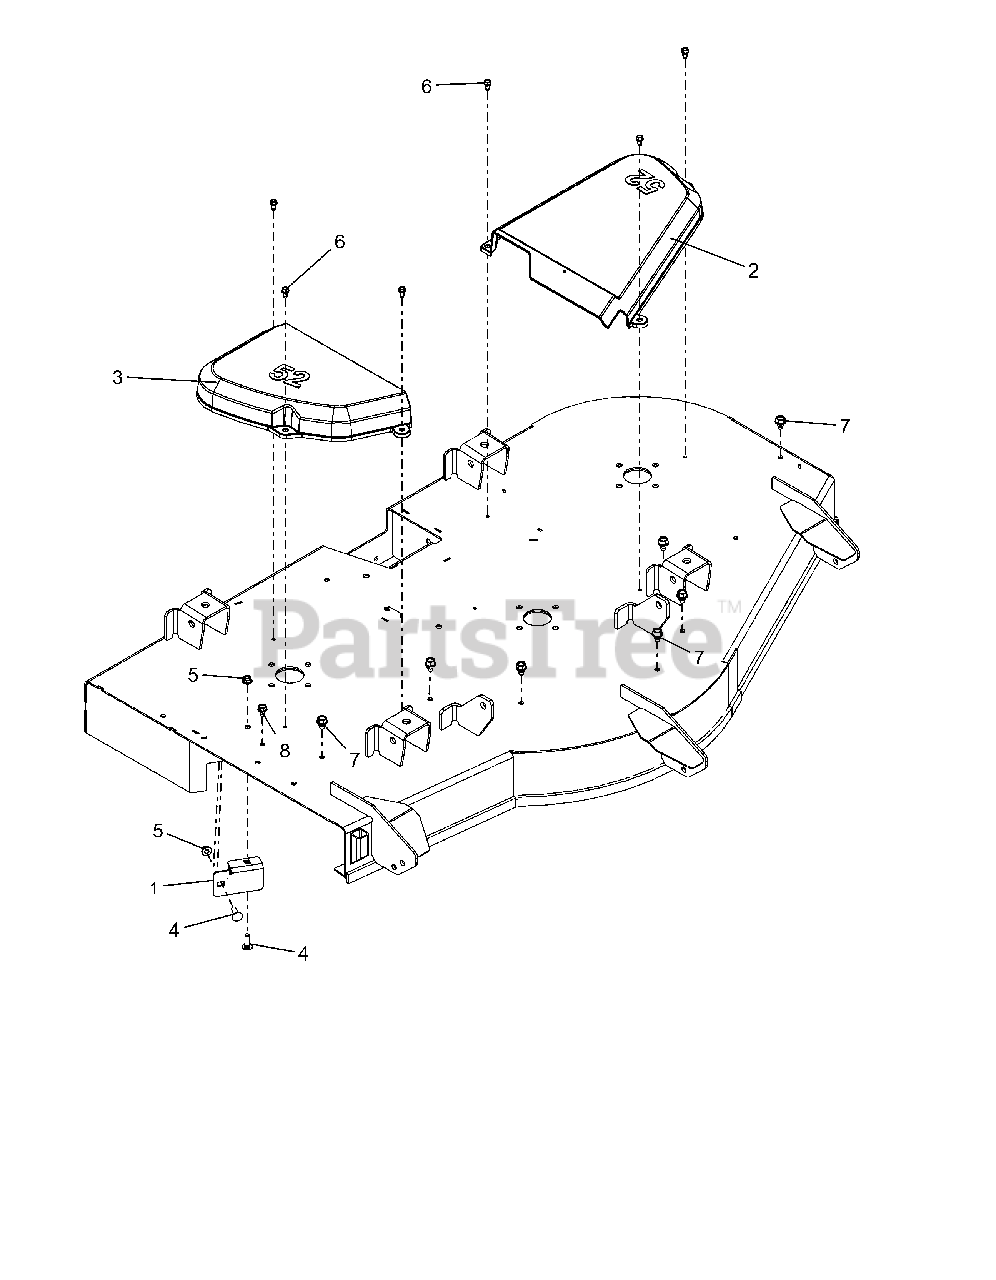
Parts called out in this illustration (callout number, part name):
1	STRIP, DEFLECTOR - 52"
2	COVER, BELT 52" LH
3	COVER, BELT 52" RIGHT
4	BLT,RHSN .31-18X1.00 G5 ZCC
5	NUT,NYL-FLG .31-18 GF ZCC
6	SCR-TAP .25-20X.50 HWH ZCC
7	SCR,TAP .375-16X.50 HWH TR ZCC
8	SCR,TAP .312-18X.50 HWH TR ZCC
